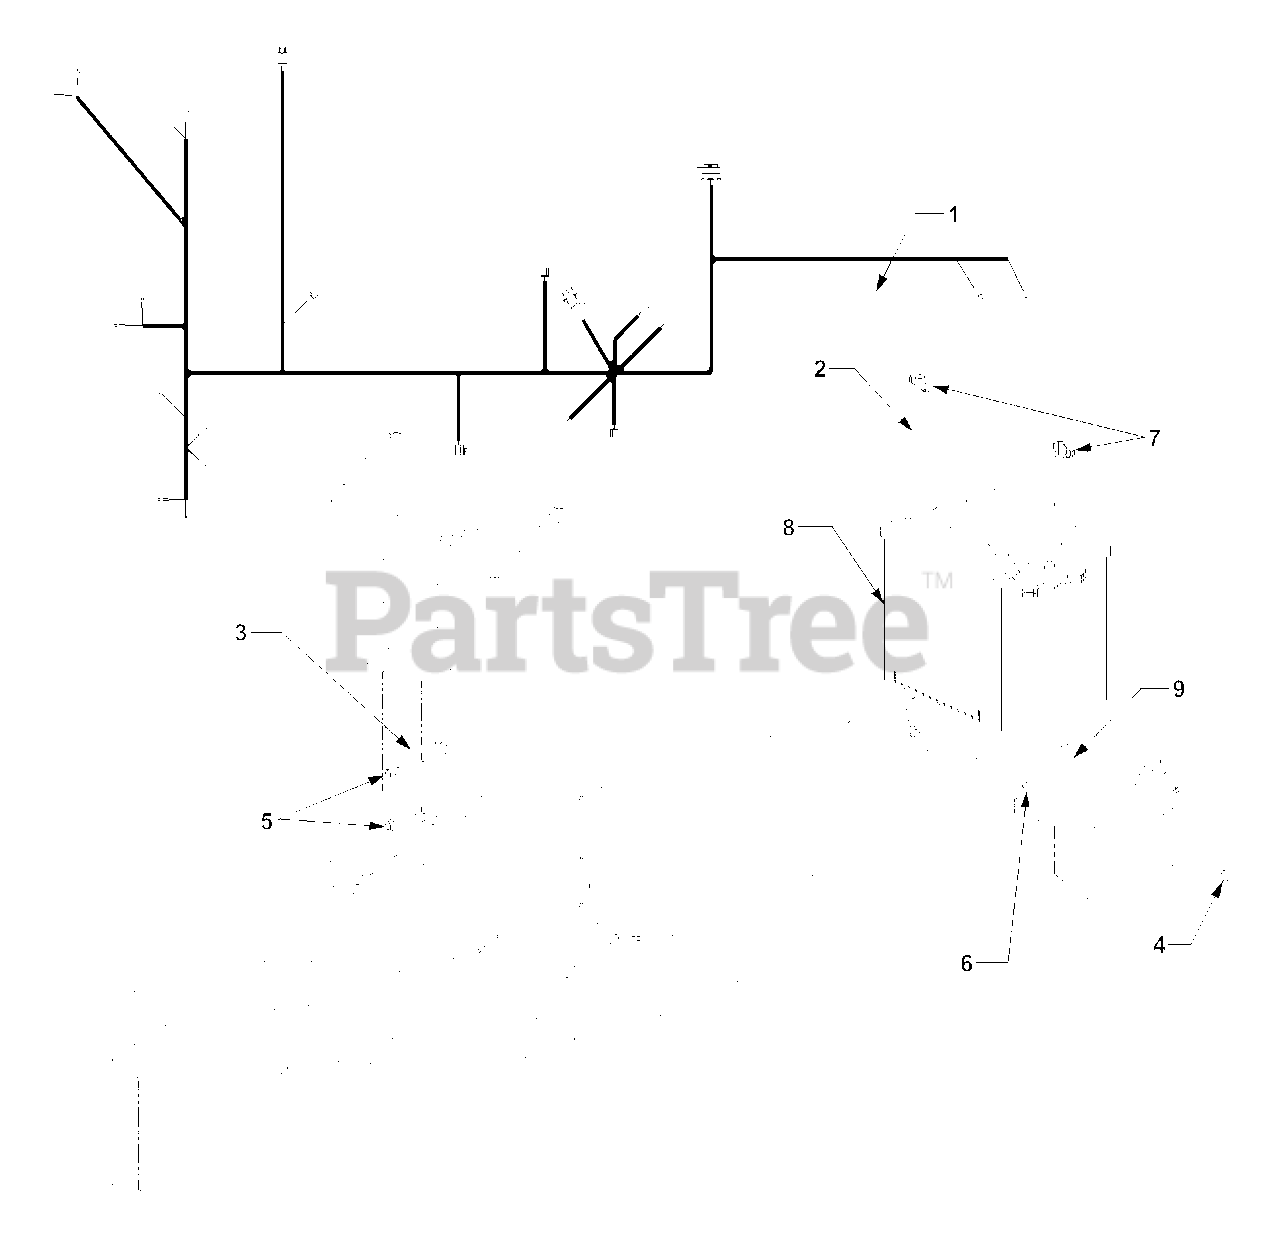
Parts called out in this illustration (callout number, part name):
1	Harness, Main Wire
2	Strap, Battery Holddown
5	Screw, Hex Wash Hd. Tapp 1/4-20 x .5
6	Nut, Hex Nylon Insert Lock, 1/4-20
7	Nut, Wing w/Bell Washer, 5/16-18
8	Battery, 500 cca Dry
9	Rod, Battery Holddown
